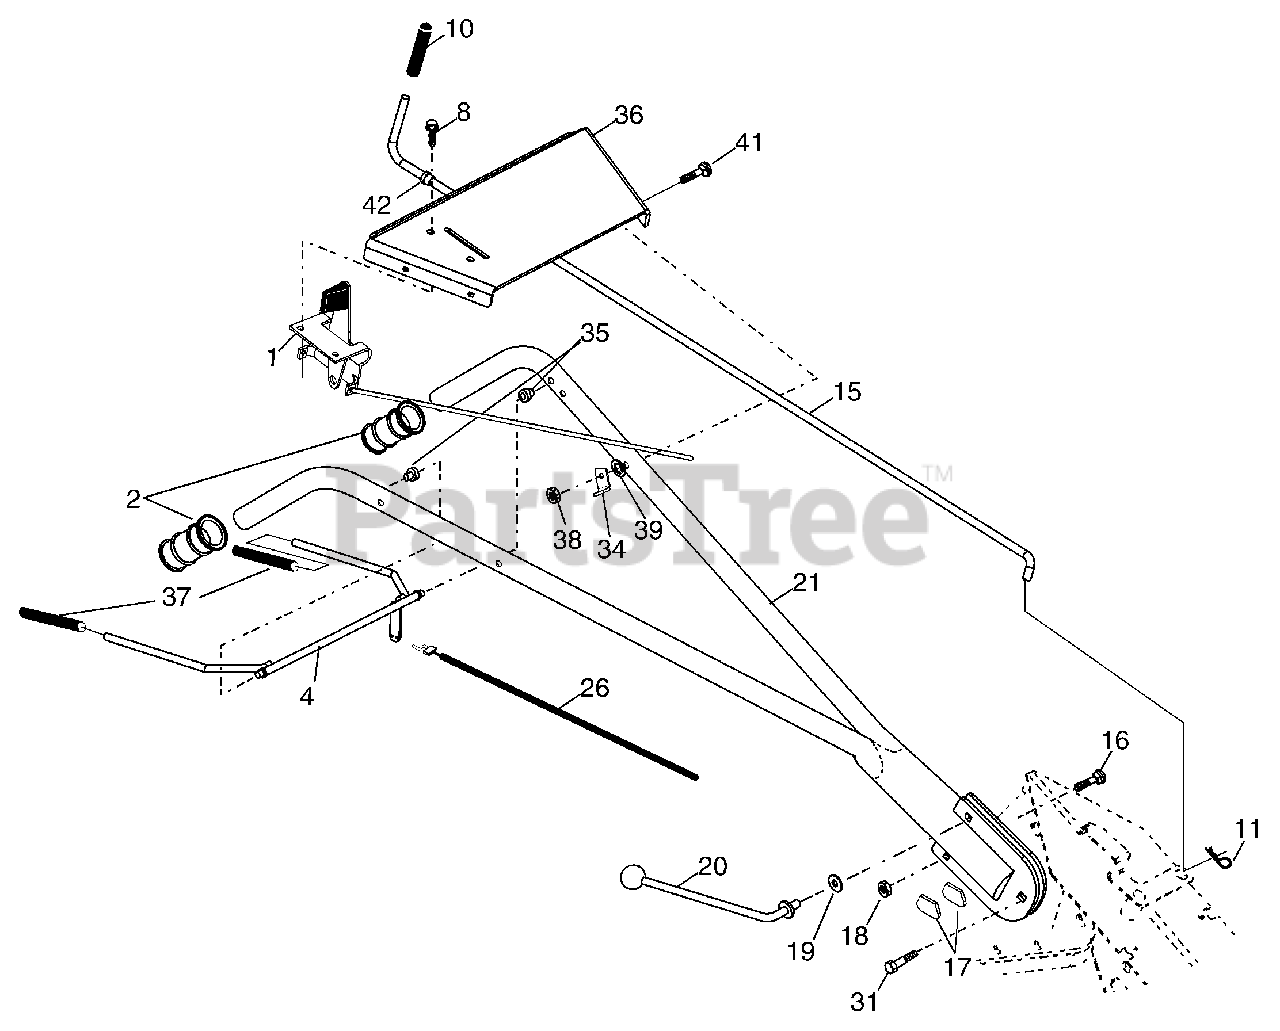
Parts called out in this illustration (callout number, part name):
1	Control, Throttle
2	Grip, Handle
4	Bar, Control
8	Screw
10	Grip, Handle
11	Clip, Hairpin
15	Rod, Shift
16	Bolt, Carriage 3/8-16 x 1 Gr. 5
17	Lock, Handle
18	Nut Crownlock 3/8-16 UNC
19	Washer 13/32 x 1 x 11 Ga.
20	Lever, Lock, Handle
26	Cable, Clutch
31	Bolt, Pivot
34	Bracket, Clutch Cable
35	Grommet, Handle
36	Bracket, Handle
37	Grip, Bar Control
38	Locknut 5/16-18
39	Washer, Lock 5/16
41	Bolt, Carriage 5/16-18 x 1-3/4
42	Bushing, Snap
